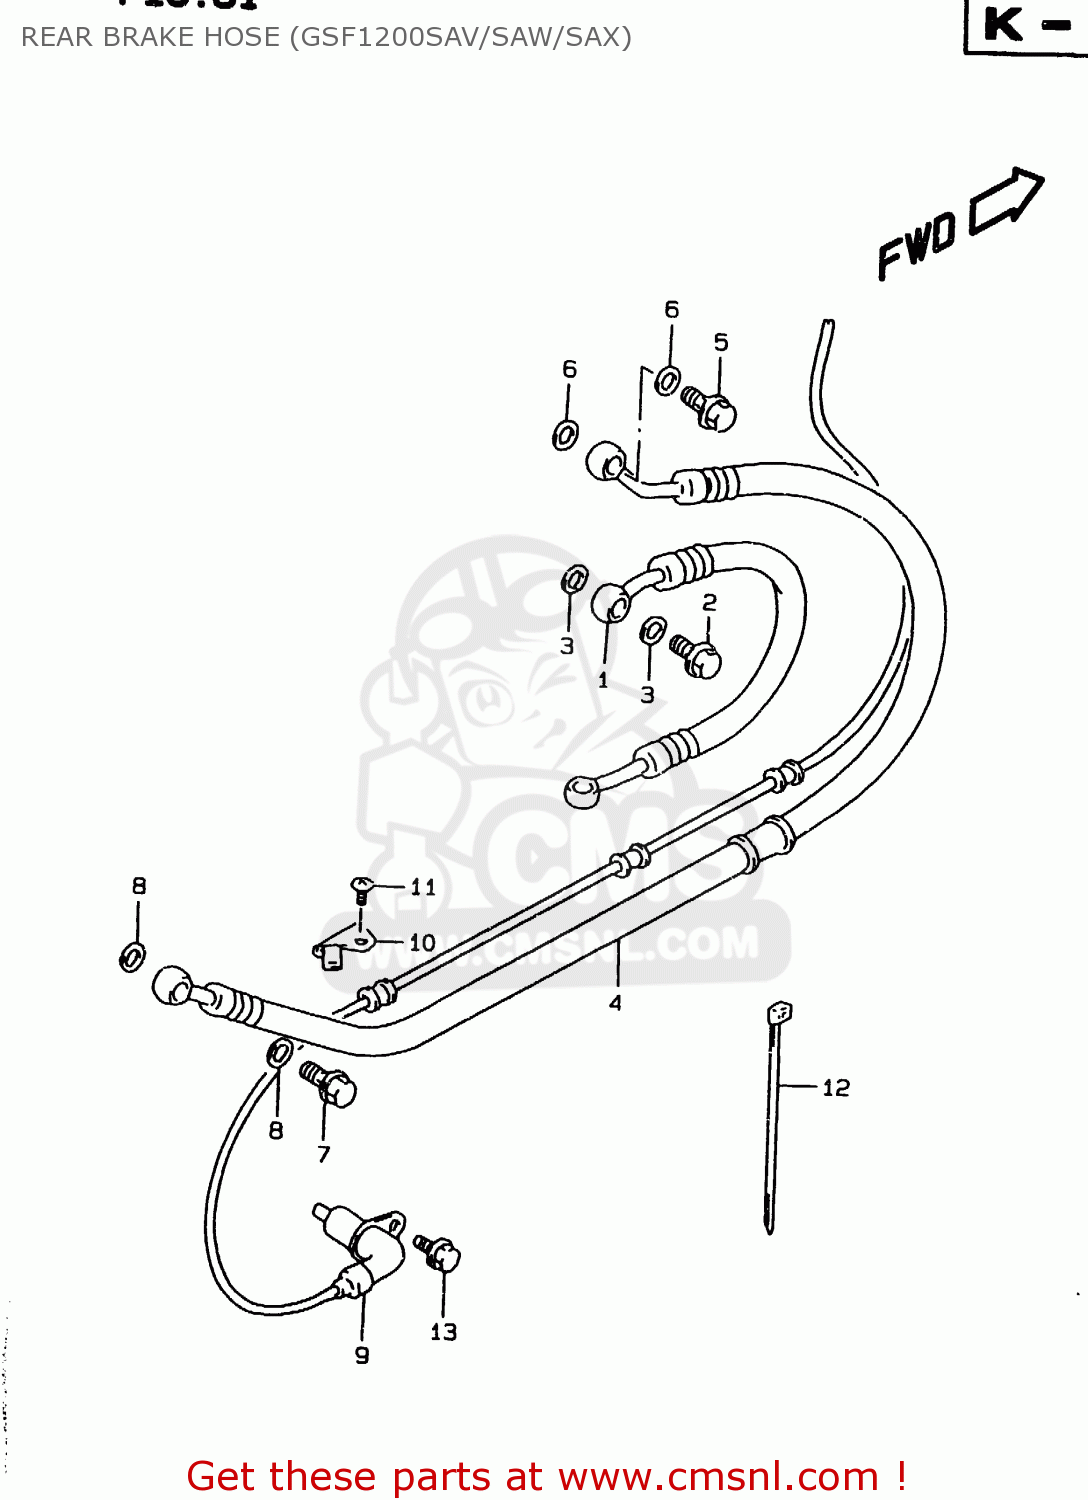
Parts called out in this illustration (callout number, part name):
1	HOSE,RR BRAKE HU IN
2	BOLT UNION
3	WASHER(10X15X1.5)
4	HOSE,RR BRAKE HU OUT
5	BOLT UNION
6	WASHER(10X15X1.5)
7	BOLT UNION
8	WASHER(10X15X1.5)
9	SENSOR,RR WHEEL ABS
10	CLAMP,ABS SENSOR RR
11	SCREW 6X10
12	CLAMP(L:145)
13	BOLT
